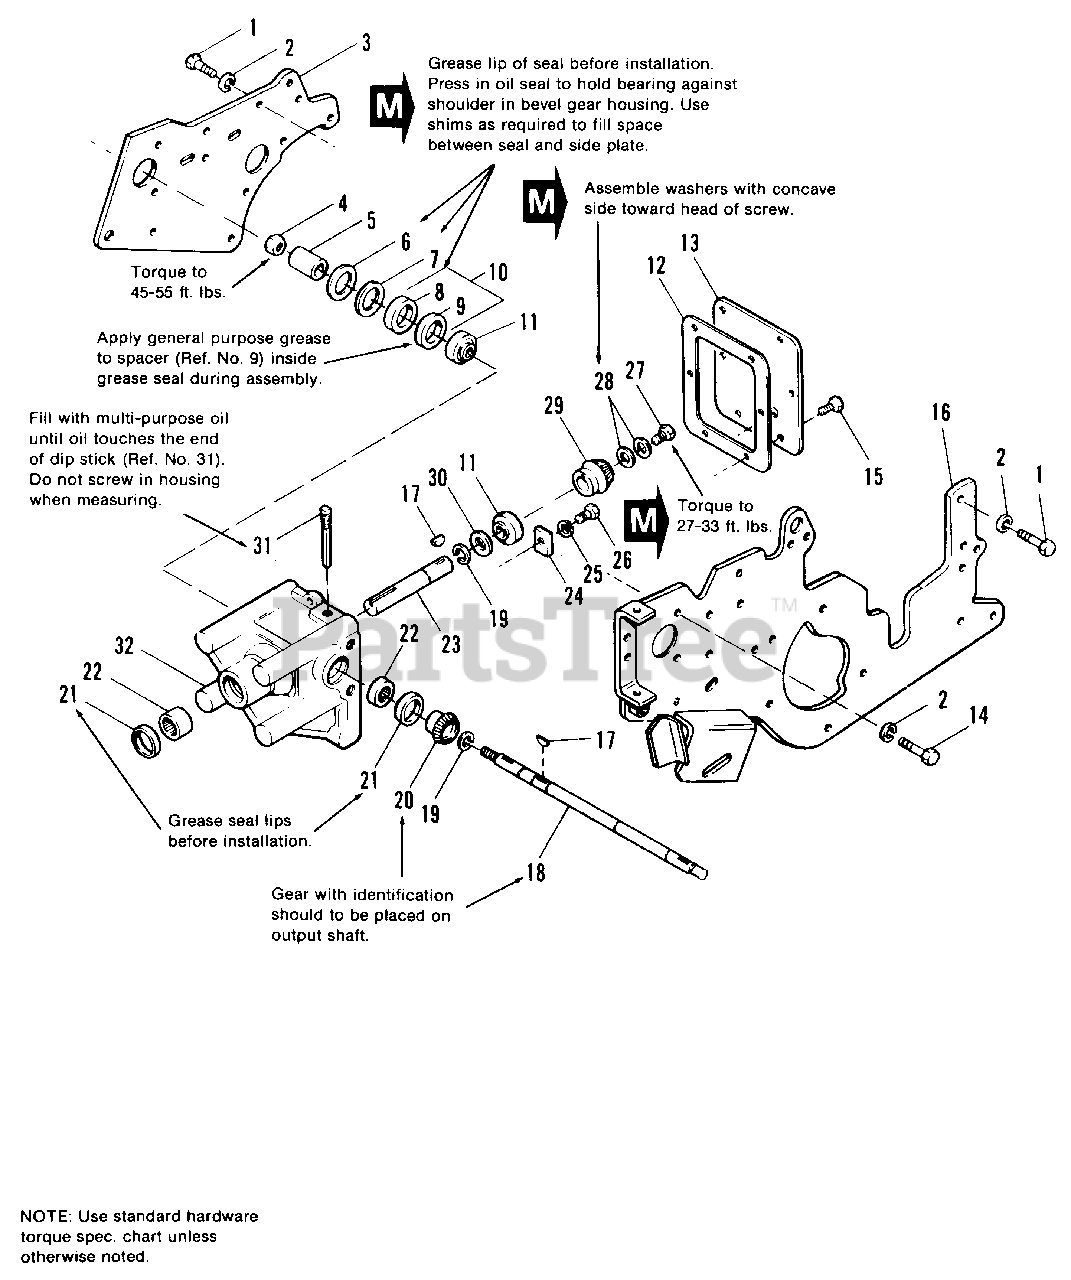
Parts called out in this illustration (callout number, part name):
1	CAPSCREW, Hex Hd., 7/16-14 x 1-1/4
2	LOCKWASHER, 7/16
3	PLATE, Side, RH
4	LOCKNUT, Hex, Jam, 3/4-16
9	SPACER, Seal, Oil
10	REPAIR KIT, Seal
11	BEARING, Ball
14	CAPSCREW, Hex Hd., 7/16-14 x 1
15	CAPSCREW, Hex Hd., 1/4-20 x 5/8
16	PLATE ASSY., Side, LH
17	KEY, Woodruff, #9
18	SHAFT, Driven
19	RING, Retaining
20	GEAR, Bevel, Driven
22	BEARING, Needle
23	SHAFT, Driver
24	PLATE, Bearing, Clamp
25	LOCKWASHER, 5/16
26	CAPSCREW, Hex Hd., 5/16-18 x 5/8
27	CAPSCREW, Hex Hd., 5/16-18 x 3/4
29	GEAR, Bevel, Driver
32	HOUSING, Bevel Gear
